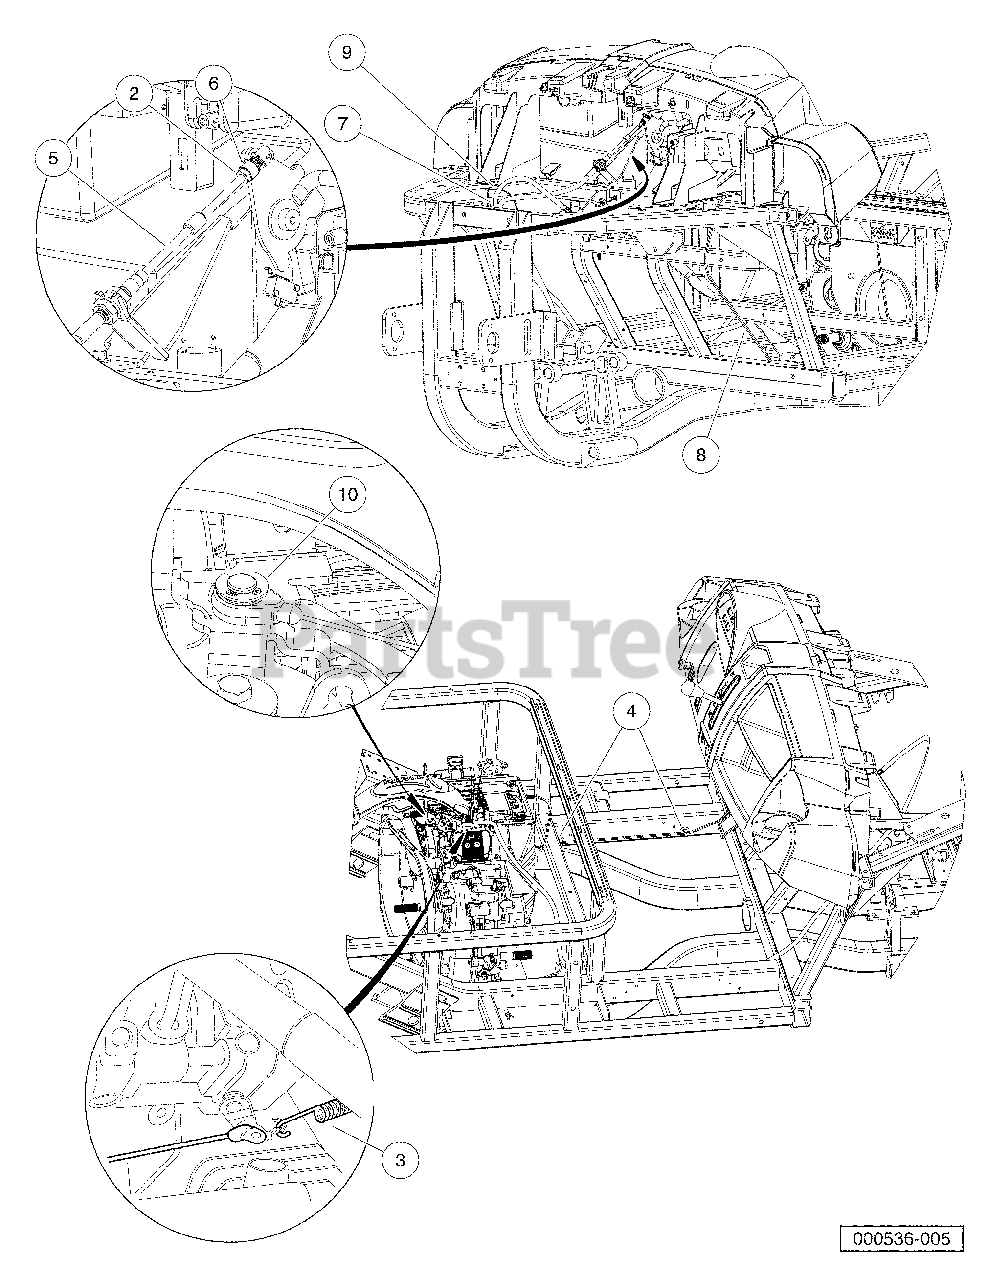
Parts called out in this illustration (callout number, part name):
1	Instl, Cable, Awd, Fh680d
2	Nut, 1/4-28 Hex Jam
4	Clip, Brake Line
5	Cable, Transmission Shift
6	Joint, Ball, .346 Dia
7	Cable, Accel, AWD, Gas, FH680D
8	Cable, Choke, AWD, FH680D
9	Tie Wrap, 8" Nylon
10	Ring, Retaining
